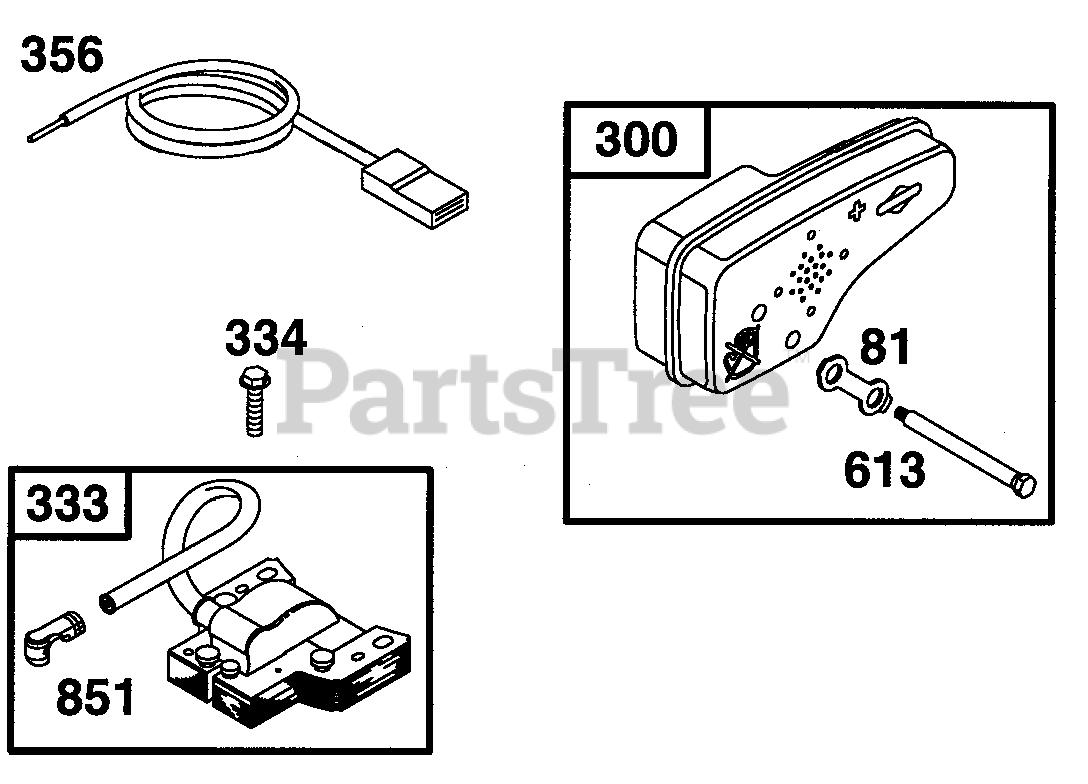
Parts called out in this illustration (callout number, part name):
81	Lock-Muffler Screw
300	Muffler-Exhaust
333	Armature-Magneto
334	Screw-Hex
356	Wire-Ground
613	Screw-Hex
851	Terminal-Ignition Cable
